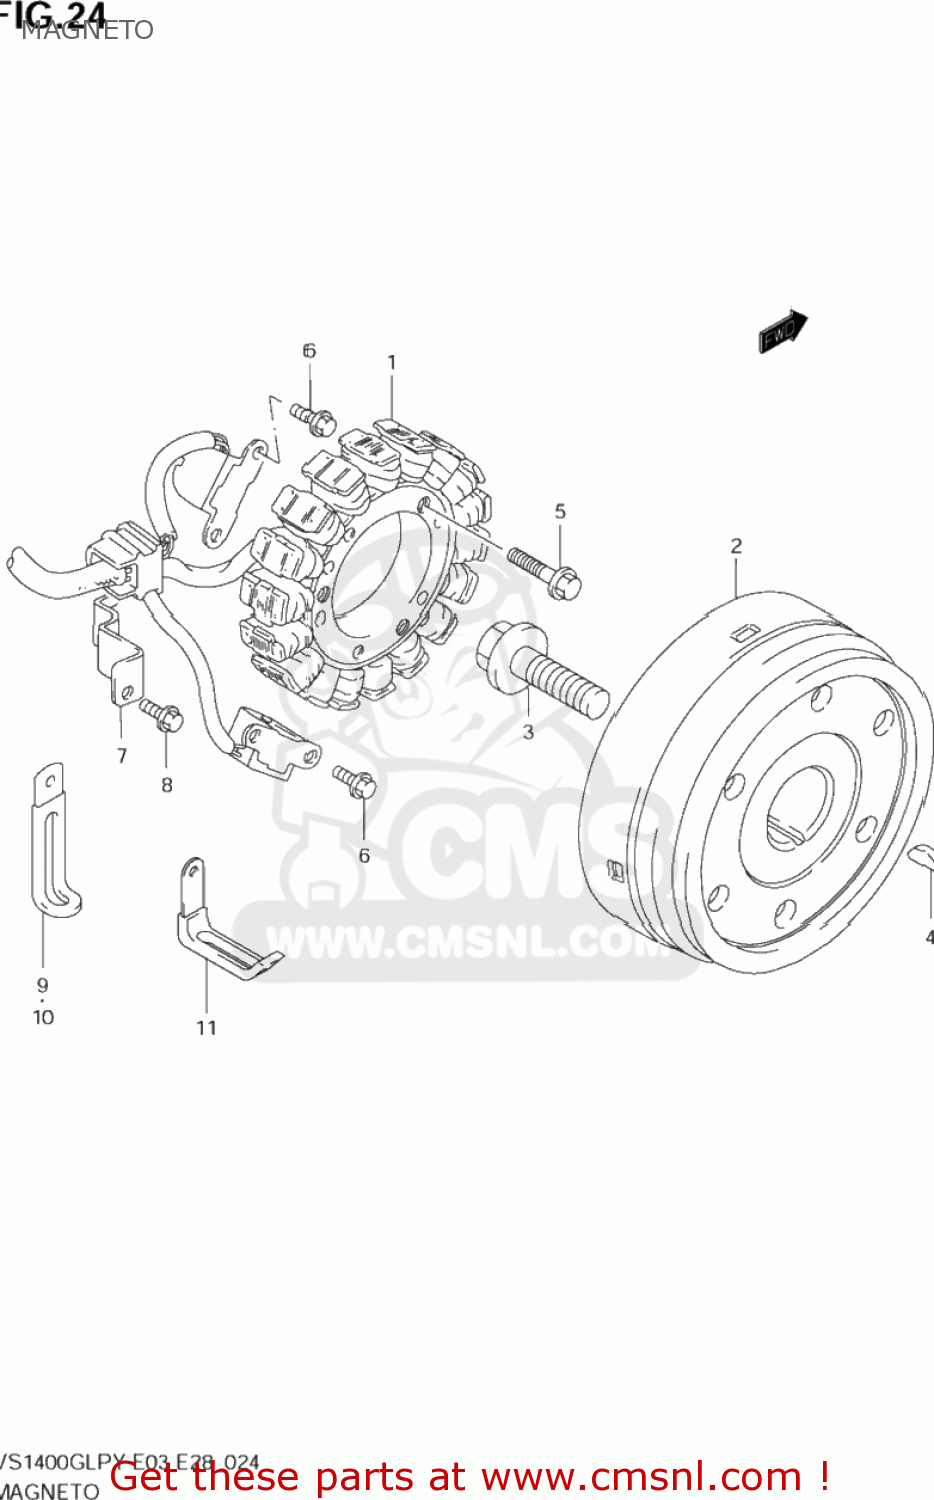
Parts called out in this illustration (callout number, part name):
1	STATOR ASSEMBLY
2	ROTOR ASSY
3	BOLT(14X43)
4	KEY
5	BOLT,G/S SWITC
6	BOLT
7	CLAMP,MAGNETO LEAD WIRE
8	BOLT
9	CLAMP(L:65)
10	CLAMP(L:45)
11	CLAMP(L:35)
